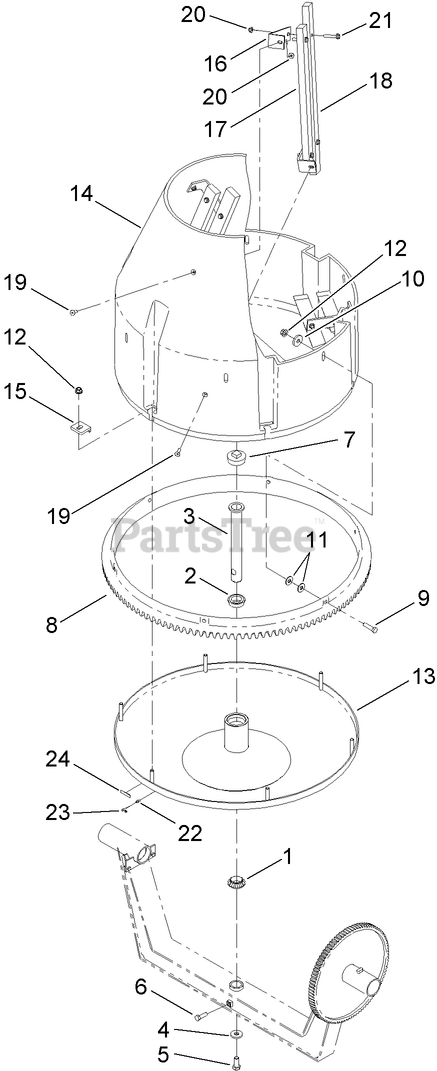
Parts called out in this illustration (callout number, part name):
1	BEARING-ROLLER
2	BEARING
3	SPINDLE
4	WASHER-FLAT
5	SCREW-HH
6	SCREW-HH
8	GEAR-RING
9	SCREW-HH
10	WASHER-FLAT
11	WASHER-FLAT
12	NUT-LOCK
14	DRUM
15	CLAMP-DRUM
16	BRACKET-PADDLE
17	PADDLE
18	PADDLE
19	SCREW-HSFH
20	NUT-HF, NI
21	SCREW-HHF
22	FITTING
23	CAP-PLUG
24	DECAL-GREASE
